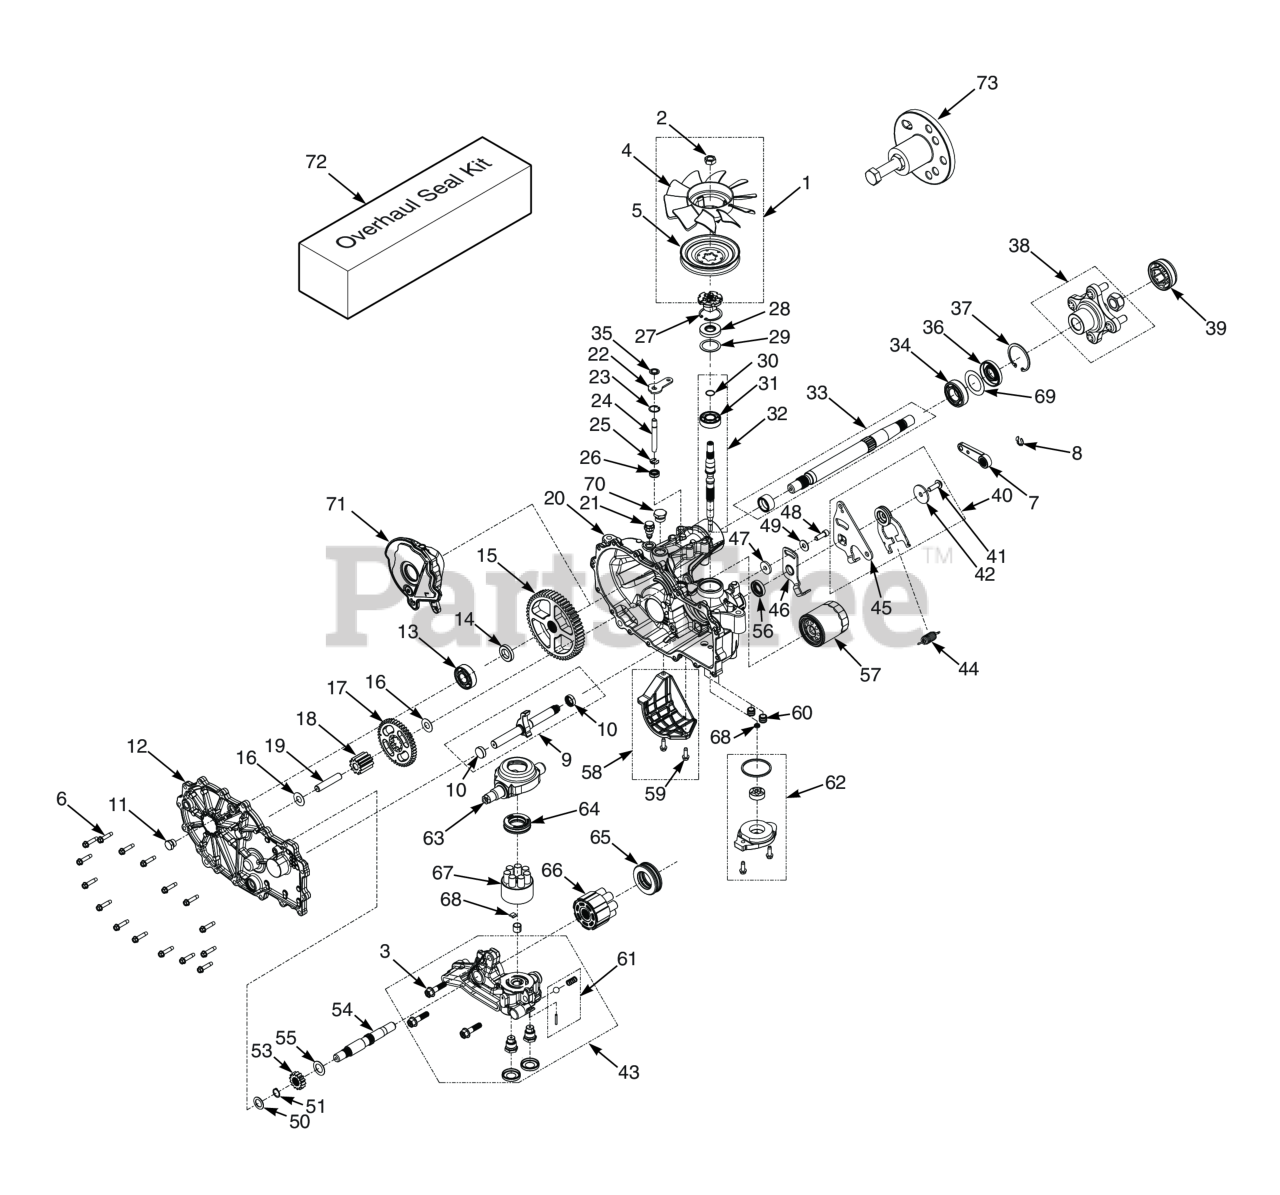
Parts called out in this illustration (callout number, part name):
1	Kit, Fan & Pulley
2	Nut, Hex Locking 1/2-20
3	Screw, Hex Flange Head 3/8-16 x 1-1/2"
4	Fan (order through Hydro-Gear)
5	Pulley, Cupped 4-1/2" Dia.
6	Bolt, Hex Head 1/4-20 x 1-1/8"
7	Handle, Brake
8	Ring, Retaining External .375"
9	Kit, Outboard, RH Rot B / LH Rot A (LH)
10	O-Ring, -111 x .103 x 424
11	Plug, External Hex Vent 9/16-18
12	Kit, Side Cover RH
13	Kit, Bearing
14	Spacer, .750 x 1.320 x .257
15	Gear, 54T
16	Washer, .5 x 1.0 x .03
17	Gear, 45T
18	Gear, 11T Steel
19	Jackshaft Pin
20	Kit, Main Housing RH Charge, Control
22	Arm, By-Pass
23	R i n g , Retaining .750 Internal
24	Rod, By-Pass
25	Ring, .Retaining .375 External
26	Seal, Lip, .375 x .75 x .25
27	R i n g , Retaining 2.06 Internal
28	Seal, Lip 17 x 40 x 7
29	Washer, 1.23 x 1.56 x .04
30	Ring, Retaining Wire
31	Bearing, Ball 17 x 40 x 12 Open
32	Kit, Input Shaft
33	Kit, Shaft, Axle
34	Bearing, Ball 1.0 x 52 x 15 Open
35	Ring, Retainging .375 External
36	Seal, Lip TC4 1.0 x 2.06 x .38
37	R i n g , Retaining 2.06 Internal
38	Hub, 4-Bolt
39	Cap, Axle
40	Kit, RTN Bi-Directional (Left Side)
41	Bolt, Hex Head Cap Screw 5/16-24 x 1" Patch
42	Washer, .343 x 1.5 x .062
43	Kit, Center Section RH
44	Spring, Extension, RTN - 44lbs
45	Arm, Control
46	Arm, Neutral (Right Side)
47	Spacer, .32 ID x 1.005 OD x .1495 Thk
48	Bolt, Hex Head Cap Screw 5/16-24 x 1" Patch
49	Washer, 7/16 x 7/8 OD x .06 HT
50	Washer, HT .62 ID x 1.0 OD x .05 Thick
51	Ring, Retaining .625
52	Pawl, Brake
53	Gear, 14T Steel
54	Shaft, Motor
55	Washer, .72 x 1.16 x .04
56	Seal, Lip 18 x 32 x 7
57	Filter, Oil
58	Kit, Filter Guard (LH)
59	Bolt, 1/4-20 x 3/4"
60	Tube, Charge Triple O-ring
61	Kit, Charge Relief
62	Kit, Charge Pump
63	Trunnion, Swashplate
64	Ball Thrust Bearing
65	Thrust Ball Bearing Assembly
66	Kit, 16cc Cylinder Block Assembly (steam
67	Kit, Cylinder Block
68	Kit, Gerotor Seal
69	Kit, Charge Relief
70	Plug, 3/4-16
71	Expansion Tank, Internal LH
72	Kit, Seal (ZT-2800)
73	Kit, Hub Puller
